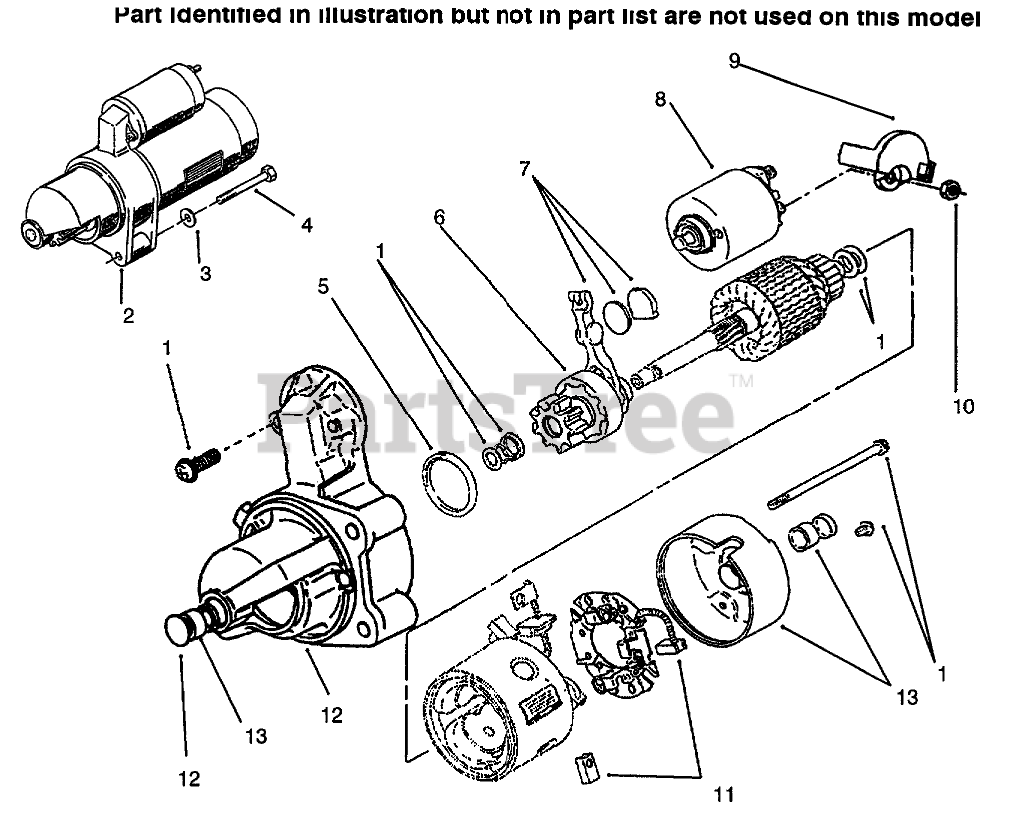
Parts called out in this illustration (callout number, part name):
2	STARTER
3	WASHER
4	SCREW
5	Dust Seal
6	CLUTCH STARTER ASSEMBLY
7	LEVER
8	STARTER SOLENOID KIT
9	Cap-Starter Solenoid
10	HEX NUT
11	BRUSH KIT
12	KIT-MTG BRKT
13	BUSHING
